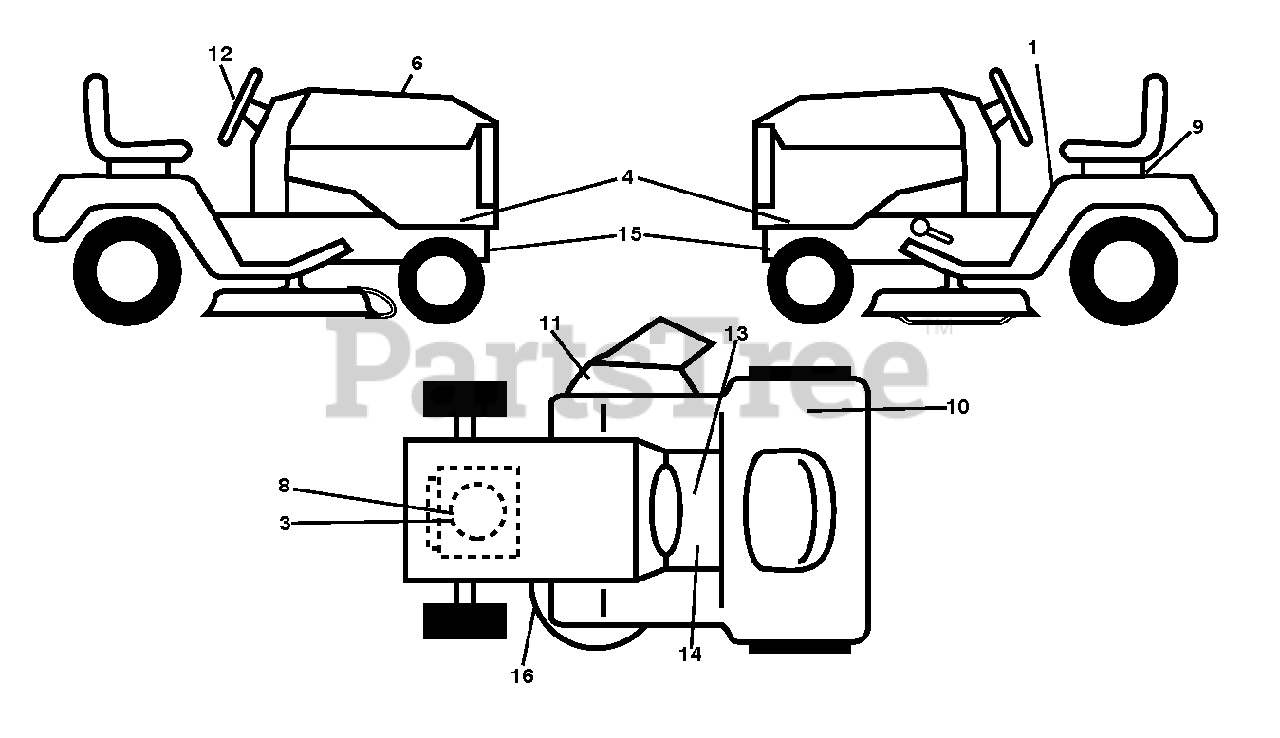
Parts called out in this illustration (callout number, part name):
9	DECAL BTRY SYMBOLS
11	DECAL, WARN. DEFLECT/CTFGR
13	DECAL PARK BRAKE
